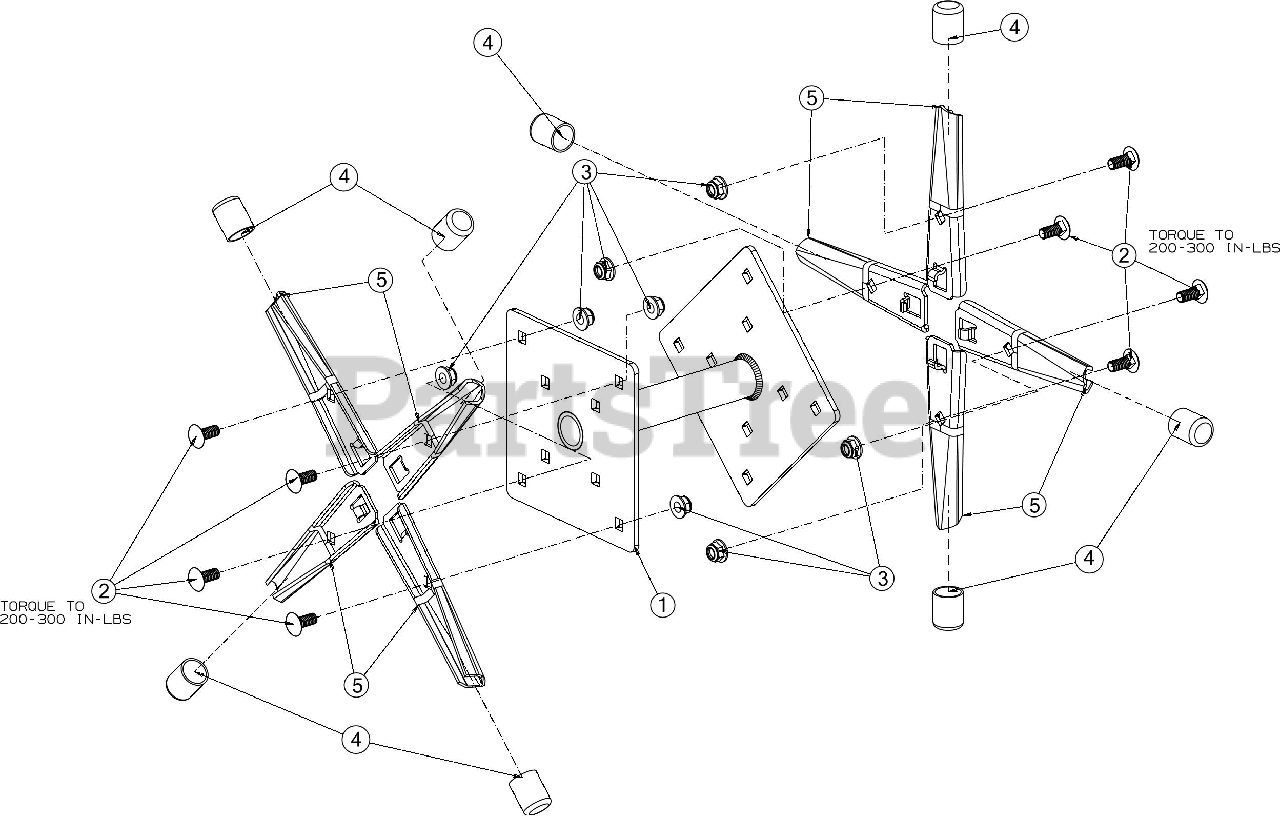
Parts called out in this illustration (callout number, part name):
1	AERATOR DOUBLE WELD ASSEMBLY
2	CARRIAGE BOLT 5/16-18 x .75
3	FLANGE LOCK NUT 5/16-18
4	CAP
5	AERATOR SPIKE
